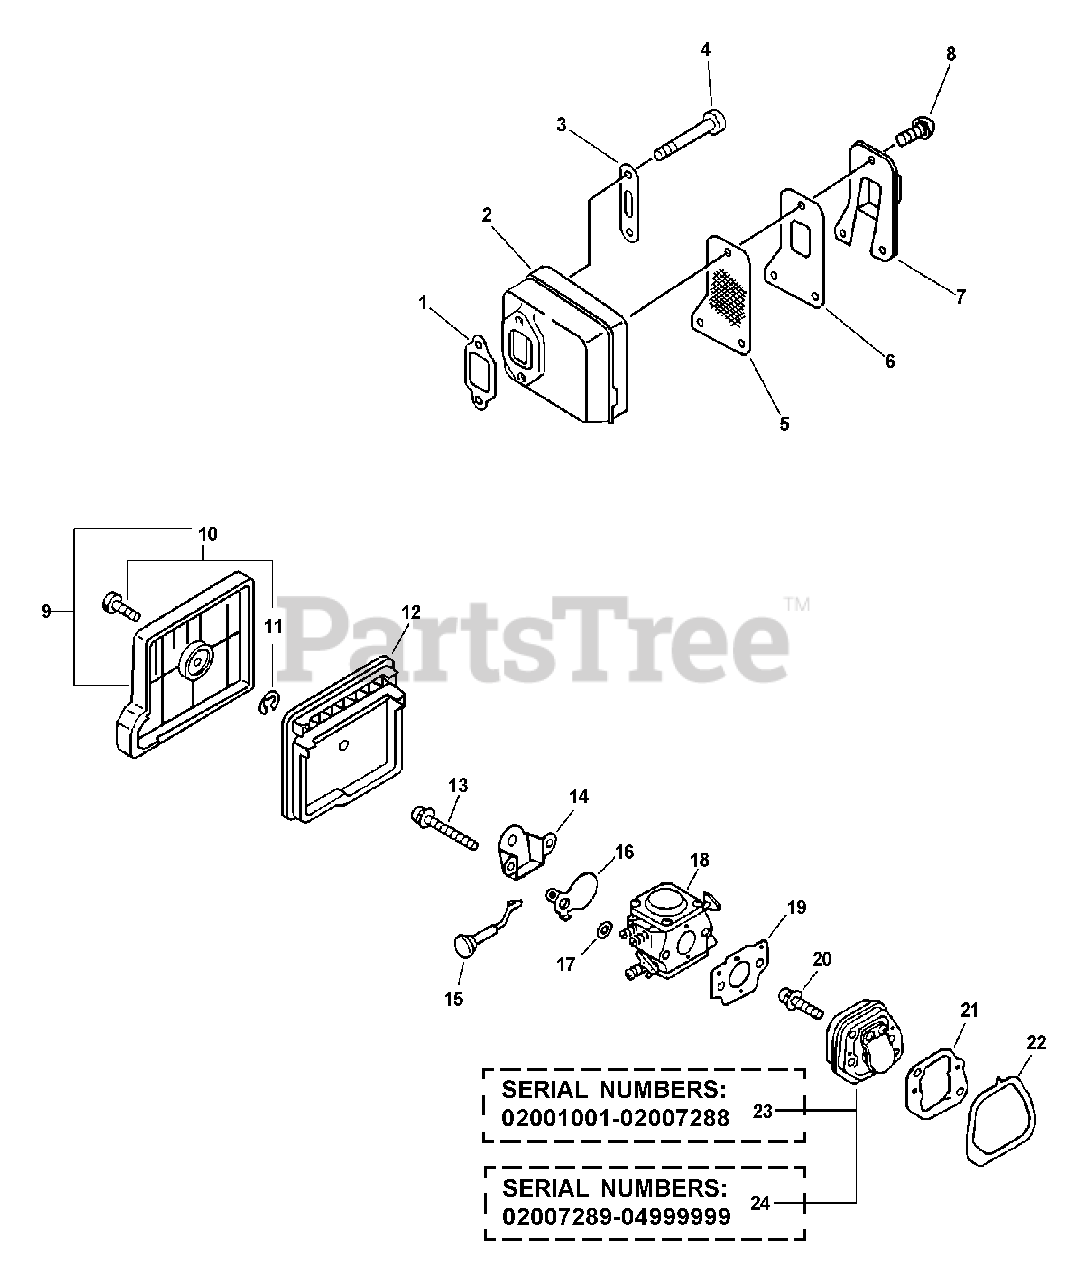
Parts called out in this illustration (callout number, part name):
1	GASKET, EXHAUST
2	MUFFLER
4	SCREW - 5X45
5	SCREEN, SPARK ARRESTOR
6	GASKET, EXHAUST
7	GUIDE, EXHAUST
8	SCREW - 4X12
9	AIR FILTER COVER ASSY
10	THUMBSCREW
11	RING, RETAINING - 4
12	FILTER, AIR
13	SCREW - 5X45
14	PLATE, PREVENT
15	ROD, CHOKE
16	SHUTTER, CHOKE
17	WASHER
18	CARBURETOR WT-589
19	GASKET, INTAKE
20	SCREW - 5X18
21	GASKET, INTAKE
22	SEAL
23	INSULATOR KIT
24	INSULATOR KIT
